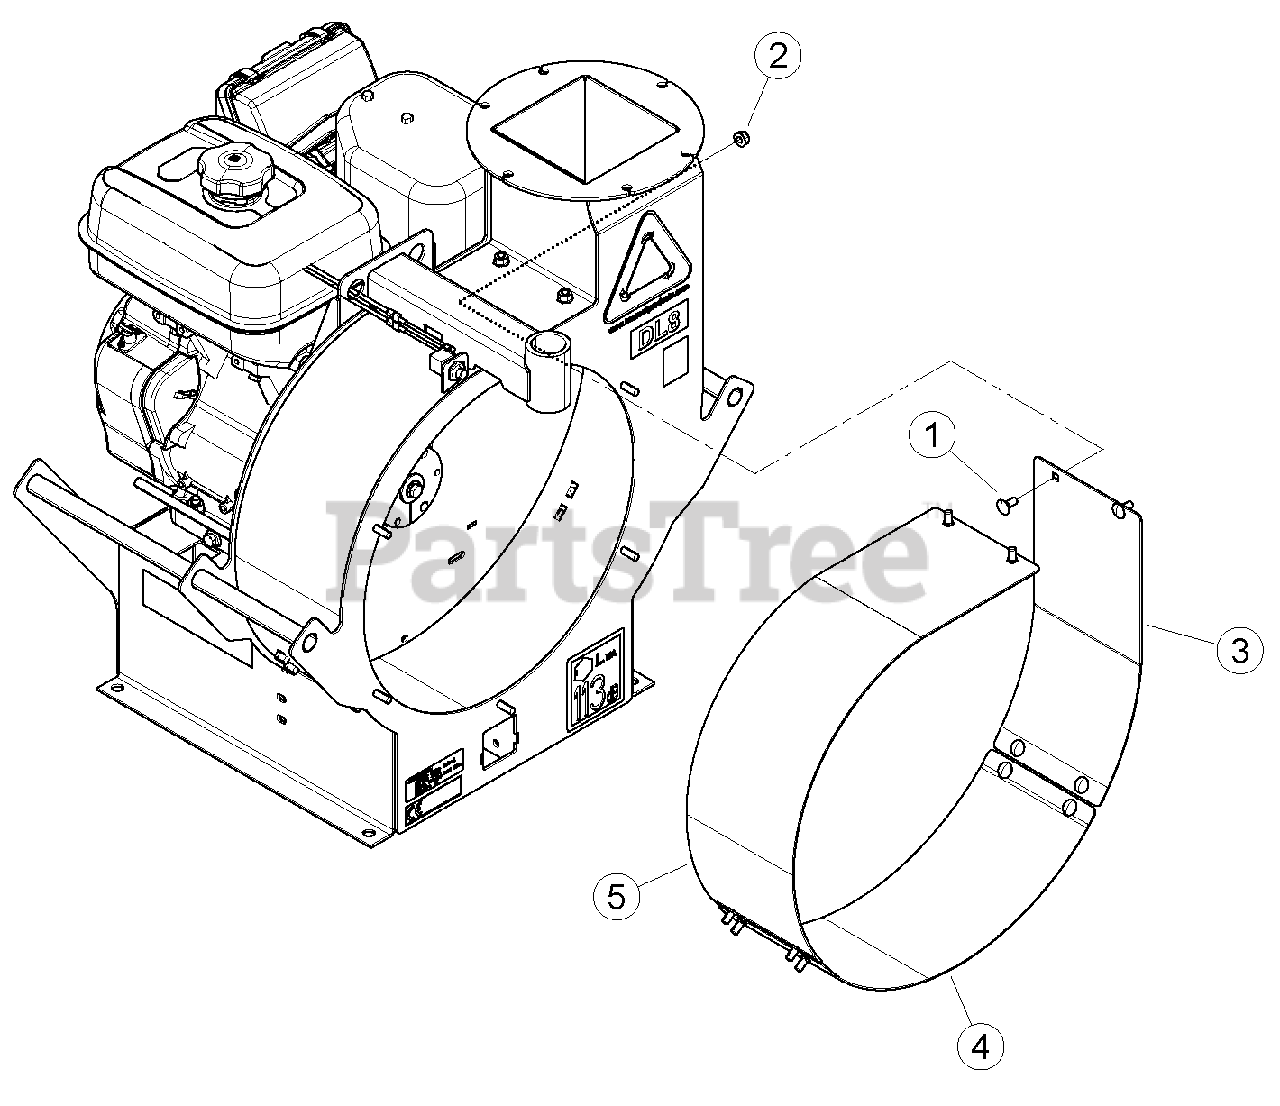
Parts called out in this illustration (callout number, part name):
1	BOLT, 5/16X3/4 GR5 NC ZP CRG
2	NUT, 5/16-18 NYLOCK FLANGE
3	LINER, WEAR RIGHT
4	LINER, WEAR MIDDLE
5	LINER, WEAR LEFT
